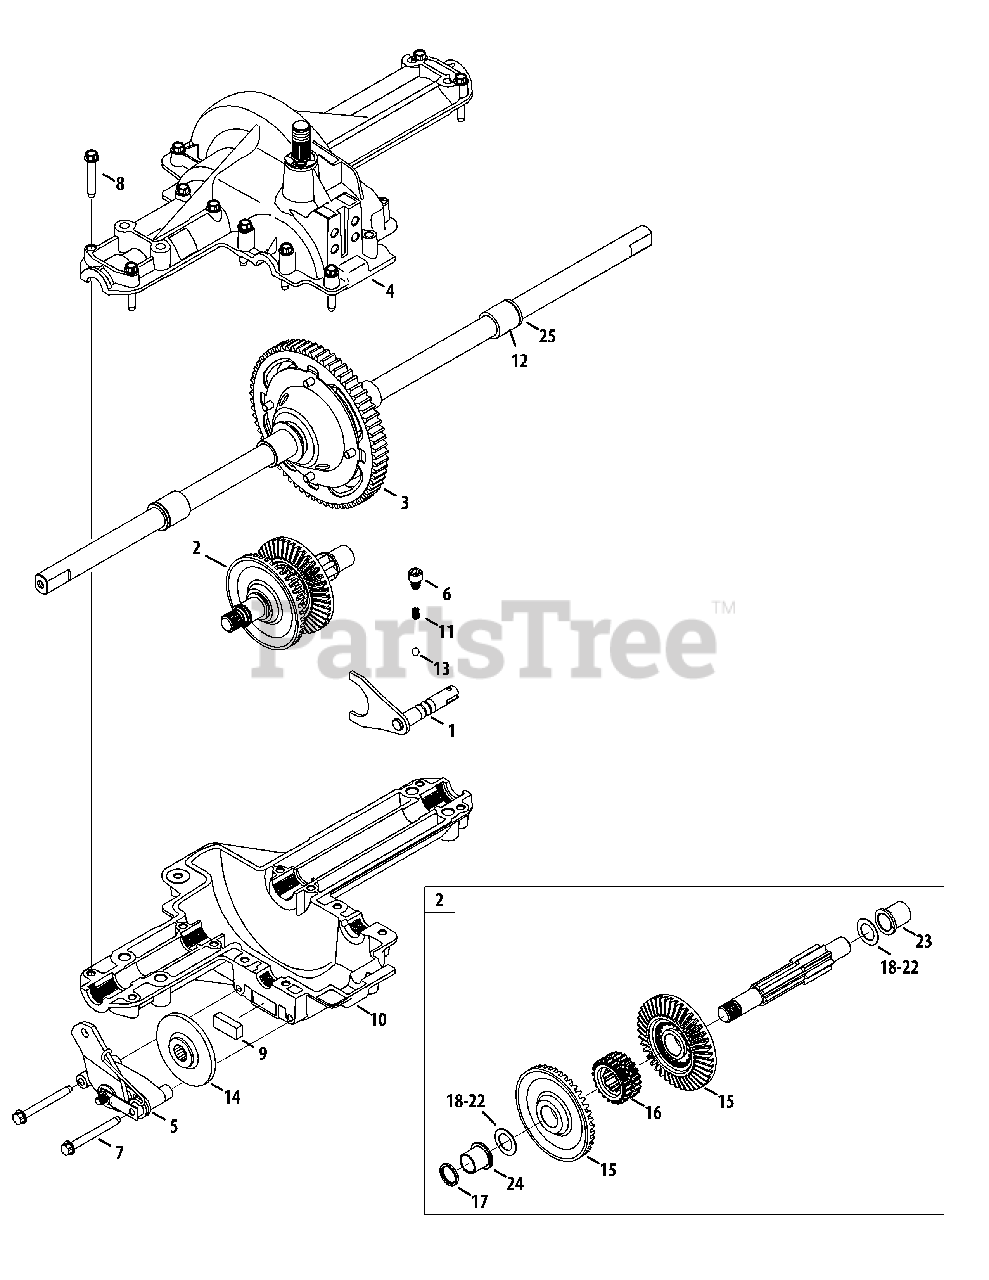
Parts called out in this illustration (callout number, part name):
1	Shaft Ass’y, Detent
2	Shaft Ass’y, Drive, Fwd-Rev
3	Differential Ass’y
4	Housing Ass’y, Upper
5	Brake Ass’y, Yoke, RH
6	Shcs, Self-tapping, 5/16-18, .375
7	Screw, Self-tapping, 1/4-20, 2.375
8	Screw, Self-tapping, 1/4-20, 1.625
9	Pad, Brake
10	Housing, Lower
11	Compression Spring
12	Bearing, Sleeve, .75 x 1.00 x .42
13	Ball, Detent, .250
14	Disc, Brake
15	Gear, Bevel, 42t, Spline
16	Collar, Clutch
17	Seal, .625 x .812 x .094
18	Washer, Flat, 5/8x1.00x.030 Hd
19	Washer, Flat, .634x1.00x.04
20	Washer, Flat, .63 x 1.00 x .020
21	Washer, Flat, .632x1.00x.035
22	Washer, Thrust, 1.00 x .632 x .020
23	Bearing, Flange, 5/8 x 3/4 x 3/4
24	Bearing, Flange, 5/8 x 3/4 x 15/16
25	Seal, .75 x 1.00 x .125
